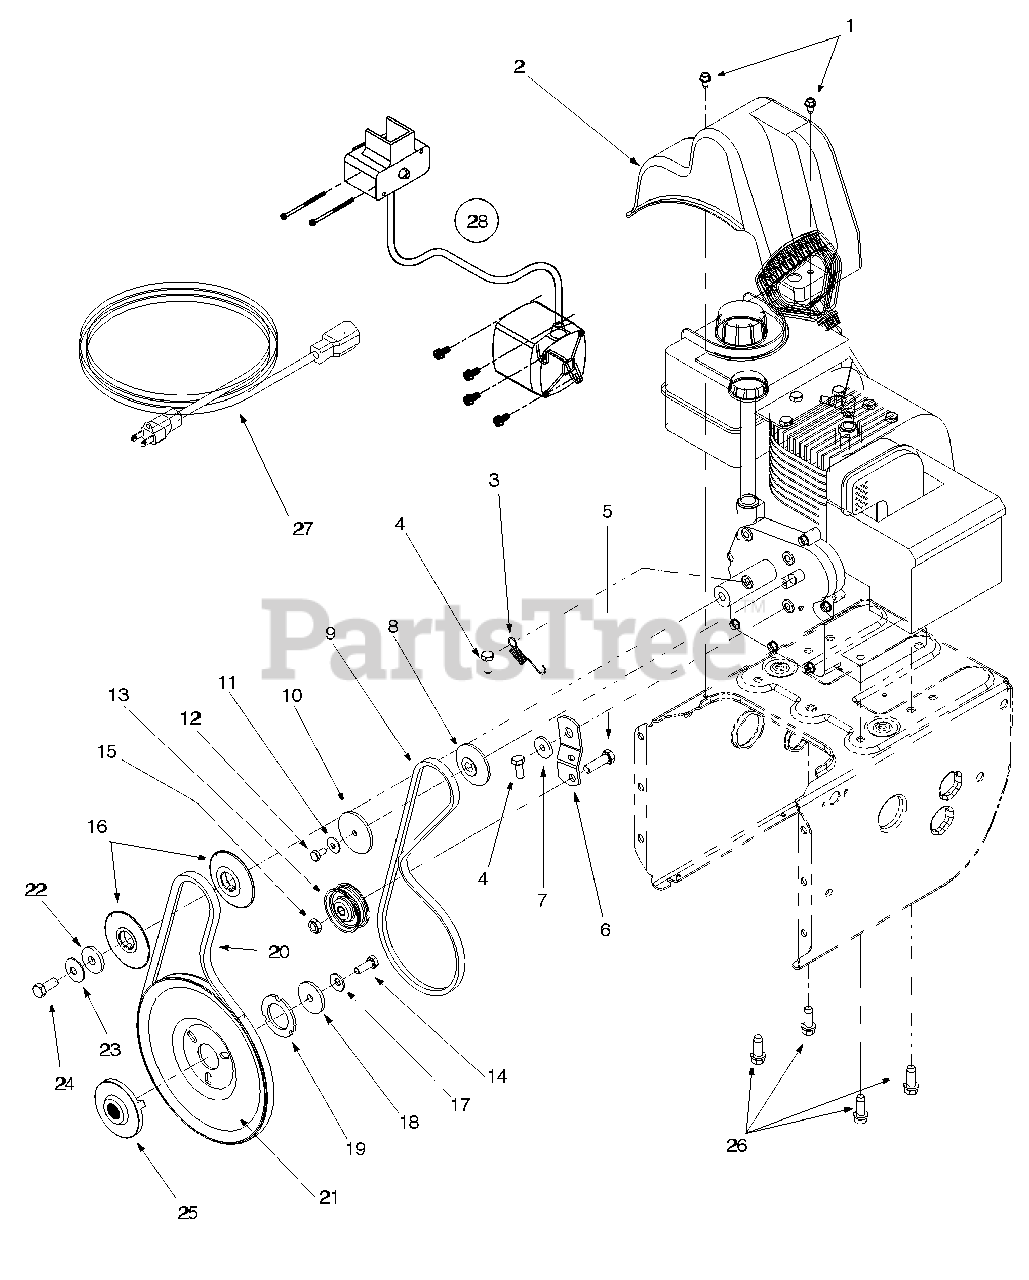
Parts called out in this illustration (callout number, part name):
1	Hex Washer Screw 1/4-20 x.625
2	Belt Cover
3	Extension Spring
4	Hex Screw 5/16-24 x .75
5	Hex Cap Screw 3/8-16 x 1.25
8	Pulley Half
9	V-Belt
10	Pulley Half
11	Bell Washer
12	Hex Cap Screw 1/4-28 x .50
13	Flat Idler
14	Lock Cap Screw 5/16-24
15	Lock Jam Nut 3/8-16
16	Pulley Half
17	Bell Washer
18	Flat Washer
19	Washer
20	Belt
21	Auger Pulley
22	Flat Washer
23	Bell Washer
24	Hex Cap Screw 3/8-24
25	Pulley
26	Hex Washer Screw 3/8-16 x 1.0
27	Extension Cord
28	Electric Start Kit
